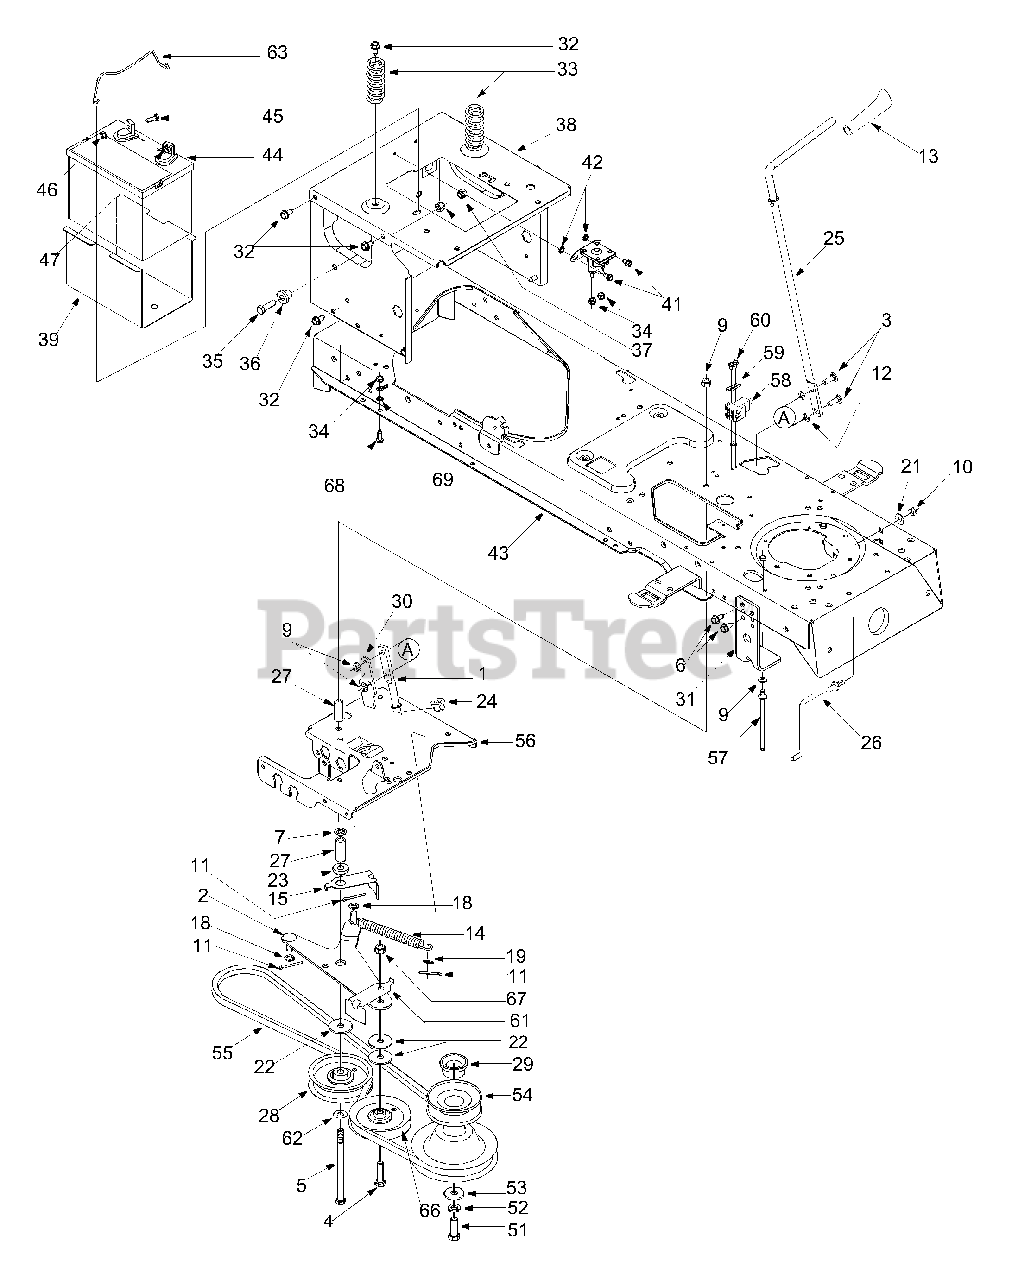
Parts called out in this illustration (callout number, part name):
1	PTO Engage Lever Assembly
4	Hex Cap Screw 3/8-16 x 1.5
5	Hex Cap Screw, 3/8-16 x 5.5
6	AB Screw 5/16-12 x 0.75
7	Push Nut, 3/8
9	Flange Lock Nut, 5/16-18
10	Hex Nut, 5/16-18
11	Cotter Pin, 1/8 x 1.25
12	Speed Nut, .3125
13	PTO Knob
14	Extension Spring, .75 x 6.75
17	Lock Washer, 5/16
18	Flat Washer, .385 x .62 x .063
19	Flat Washer, 5/16
23	Shoulder Spacer, .380
24	Hex Split Flange Bearing, .5
26	Belt Keeper Rod
27	Spacer, 3/8 x 1.54
28	Idler Pulley, 3.5
32	Self Tapping Screw, 5/16-18 x .625
33	Compression Spring, 1.28 x 3.125
34	Lock Nut 1/4-20
35	Shoulder Screw, .625 x .5, 7/16-20
36	Bell Washer, .45 x 1.0 x .062
37	Flange Lock Nut, 7/16-20
41	Self Tapping Screw, 1/4-20 x .5
42	Lock Washer, 1/4
45	Hex Cap Screw, 1/4-20 x .62
46	Hex Sems Nut, 1/4-20
47	Wing Nut, 1/4-20
48	Extension Spring, .50 x 5.0
49	Hex Cap Screw, 5/16-18 x 1.75
50	Spacer Cup
51	Hex Head Cap Screw, 7/16-20 x 1.25
52	Lock Washer, 7/16
53	Flat Washer, .450 x 1.25
54	Engine Pulley, 3.56 OD x 5.56
55	V Belt
57	Keeper Pin, 5/16 x 4.75
58	Switch
59	Switch Plate
60	Screw, #10-16 x .5
61	Belt Guard
63	Battery Hold-Down Rod
66	Idler Pulley
67	Hex Lock Nut 3/8-16
68	TT Screw 1/4-20 x 0.75
69	Shoulder Screw
